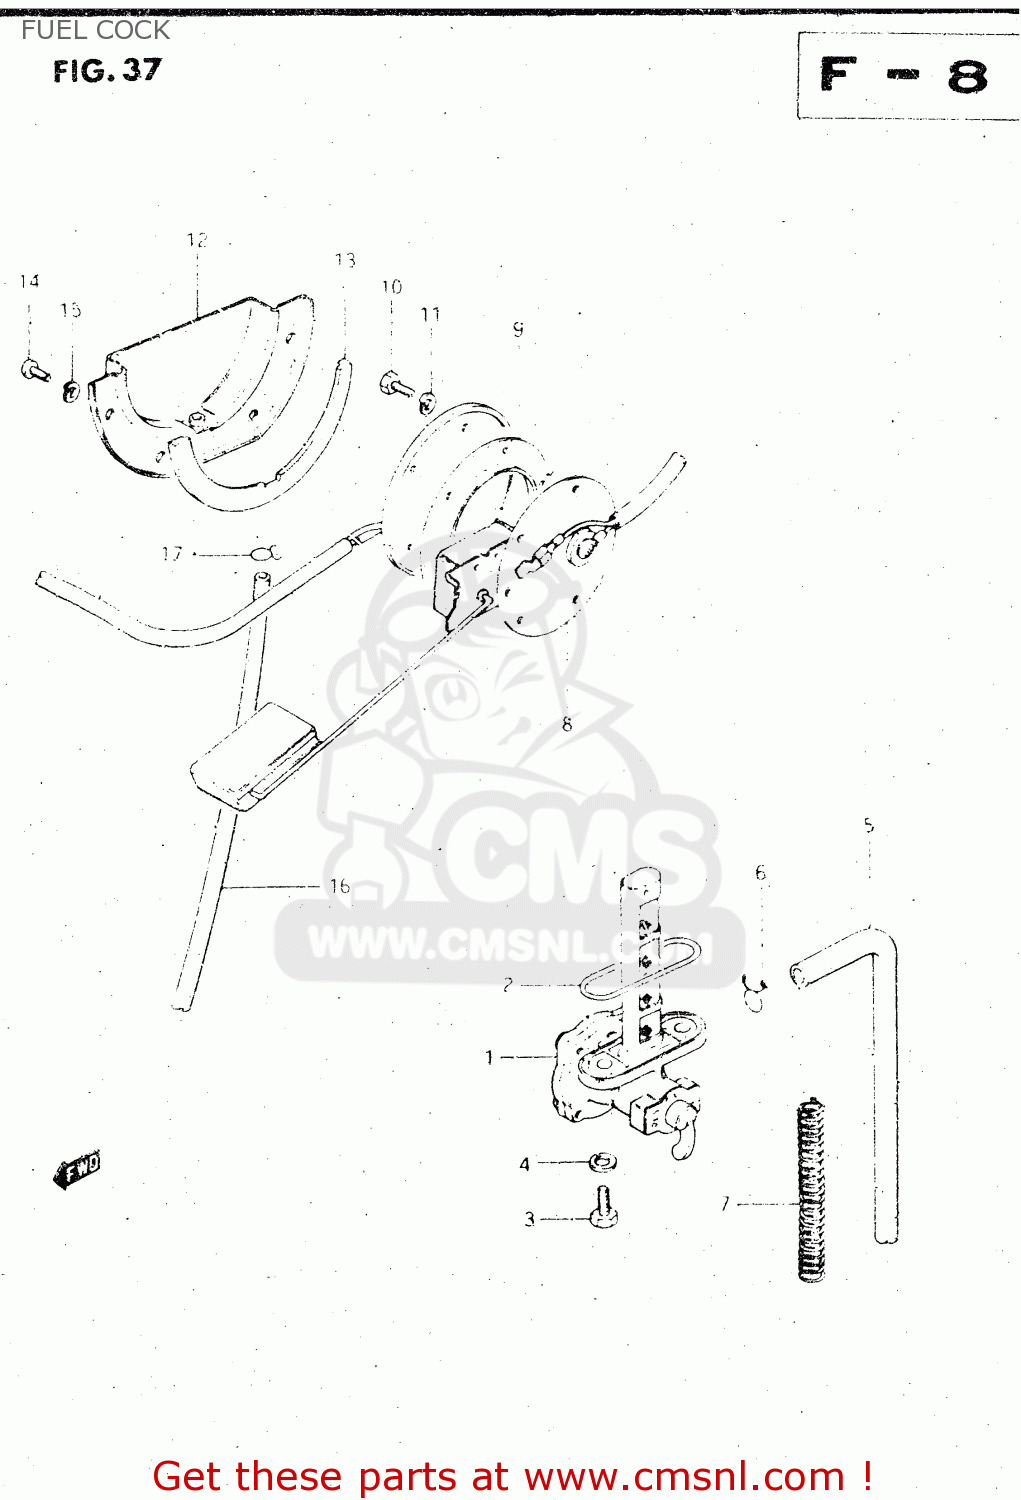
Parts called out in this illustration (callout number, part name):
1	COCK ASSEMBLY,FUEL
2	O RING
3	BOLT(6X20)
4	GASKET
5	HOSE
6	CLIP
7	SPRING
8	GAUGE ASSEMBLY,FUEL LEVEL
9	GASKET,FUEL LEVEL GAUGE (NAS)
10	BOLT 5X10
11	LOCK WASHER
12	PLATE,FUEL DRAIN
13	GASKET (NAS)
14	SCREW
15	LOCK WASHER
16	HOSE,FUEL
17	CLIP
